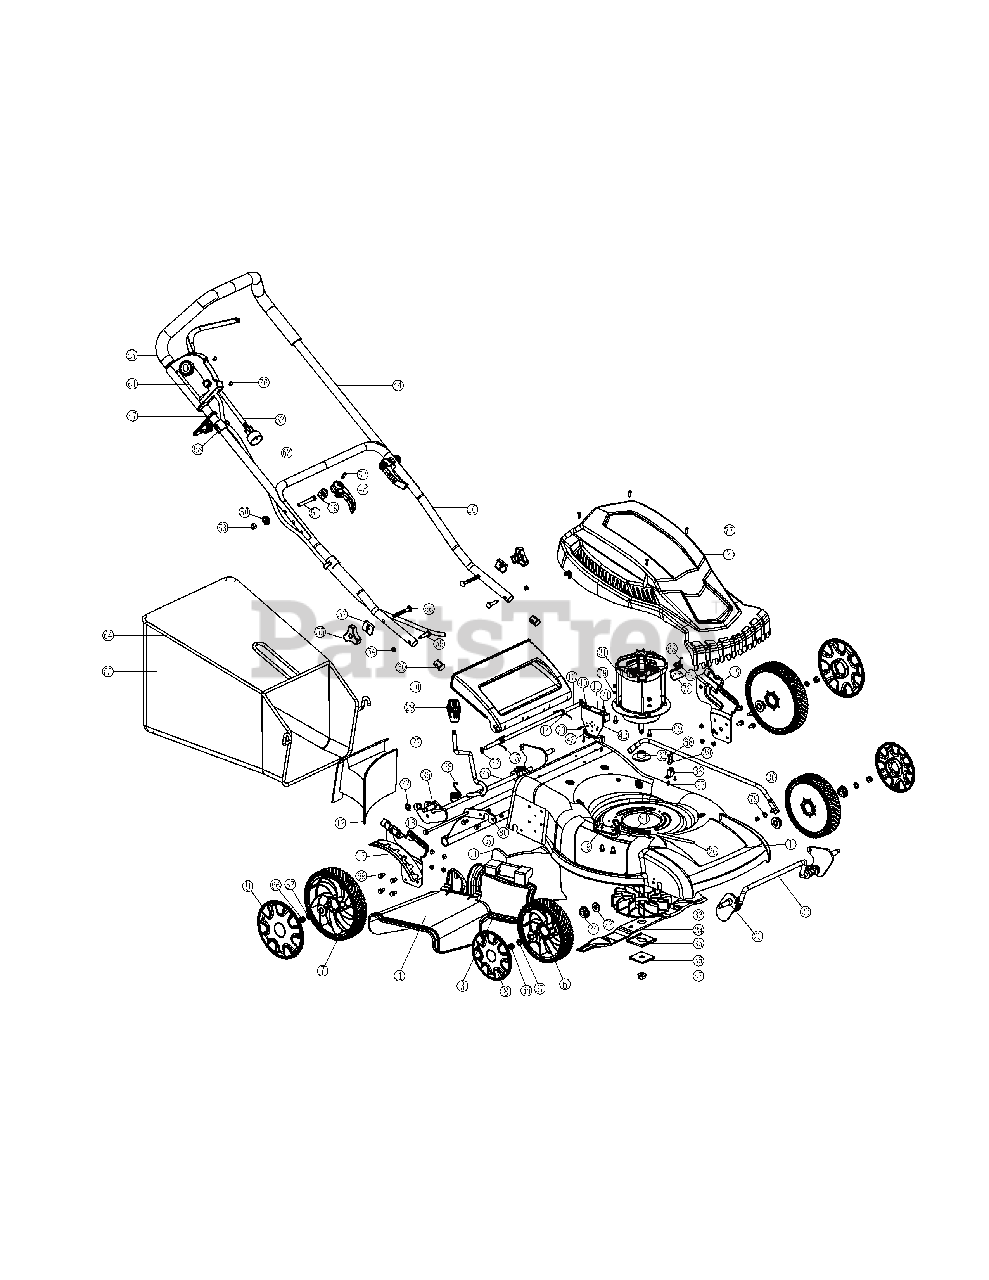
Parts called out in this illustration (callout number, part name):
3	Mulch Door
4	Discharge Chute
5	Trail Shield
6	Front Wheel
7	Rear Wheel
9	Shroud Seal
11	Rear Baffle
12	Mulch Plug
16	Left Bracket
17	Right Bracket
18	Trailshield Rod
19	Mulch Door Bracket
20	Mulch Door Rod
21	Mulch Door Spring
22	Front Shaft Assembly
23	Spacer Bushing
24	Wheel Bushing
25	Rear Shaft Assembly
26	Spacer Bushing
27	Height Adjust Handle
28	Height Adjust Spring
29	Height Adjust Knob
30	Height Adjust Rod
31	Motor
33	Electric Motor Fan
34	Blade
38	Strain Relief Bracket
39	Strain Relief Cap
41	Resistor Holder
42	Resistor Bracket
43	Resistor Base
44	Upper Handle
45	Handle Grip
46	Lower Handle
47	Cord Retainer
48	Quick Release Handle
50	Quick Release Knob
51	Quick Release Pin
54	Nylock Nut
59	Shoulder Bolt
61	Switch Box Assembly
62	AC Power Cord
63	Motor Cord
64	Grassbag Frame
68	Screw, M4.2 x 16
69	Screw, M6 x 12
70	Lock Nut, M6
71	Screw, M4 x 12
72	Lock Nut, M4
74	Rectifier Heat Sink
76	Screw, M4.8 x 16
77	Screw, M4.2 x 25
78	Screw, M5 x 12
79	Screw, M4.2 x 16
80	Spring Washer
